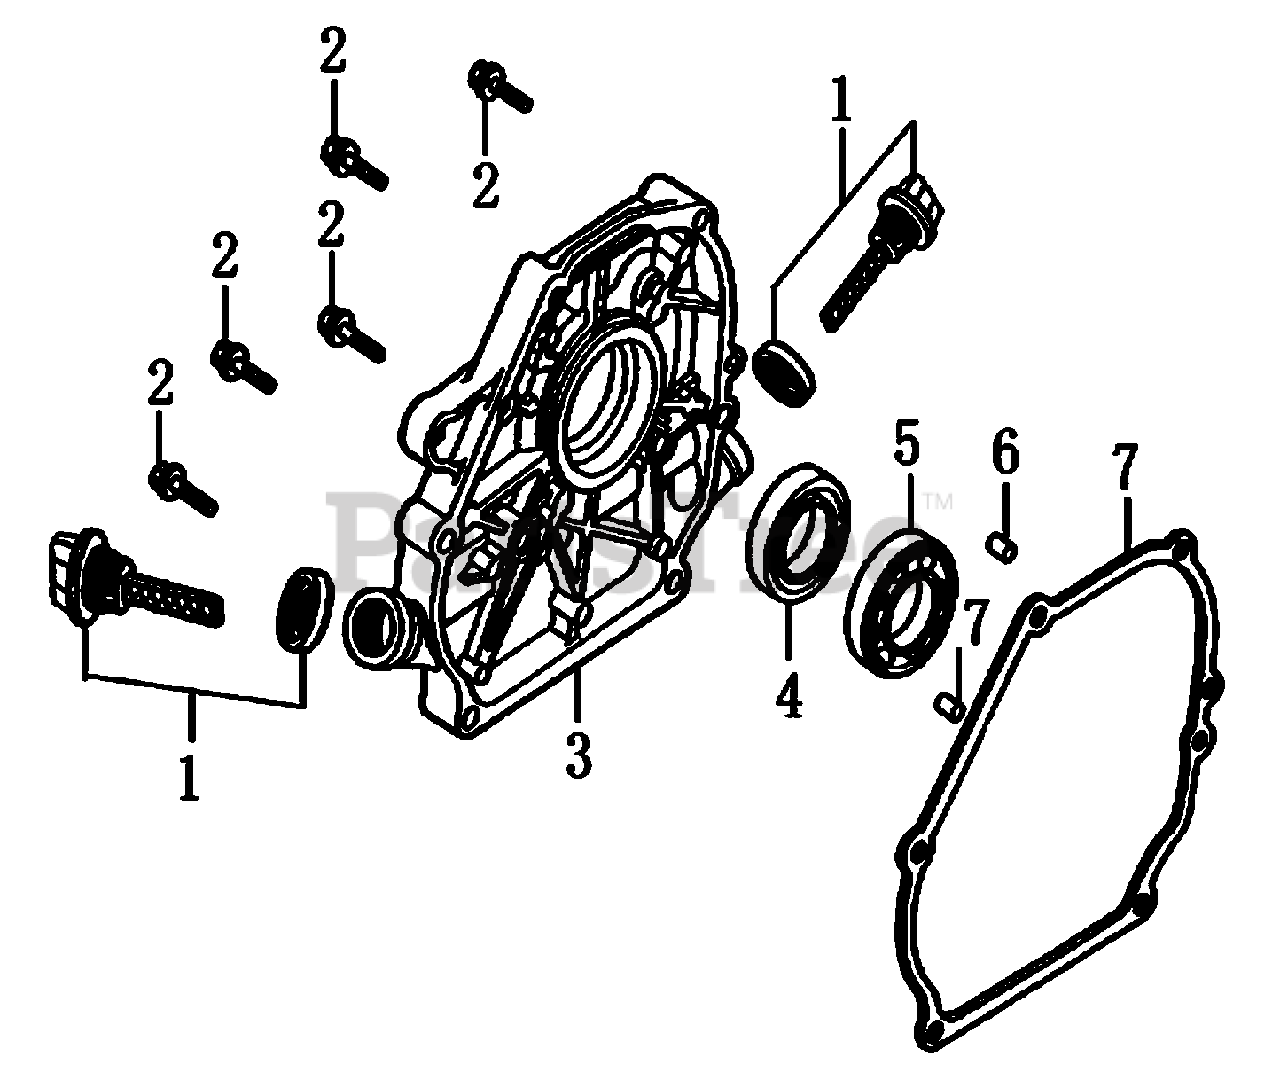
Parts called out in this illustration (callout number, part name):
1	GAUGE ASSY.,OIL LEVEL
2	BOLT, FLANGE
3	CASE COVER
4	OIL SEAL 25X41.25X6
5	BEARING, RADIAL BALL
6	PIN, DOWEL
7	GASKET, CASE COVER
